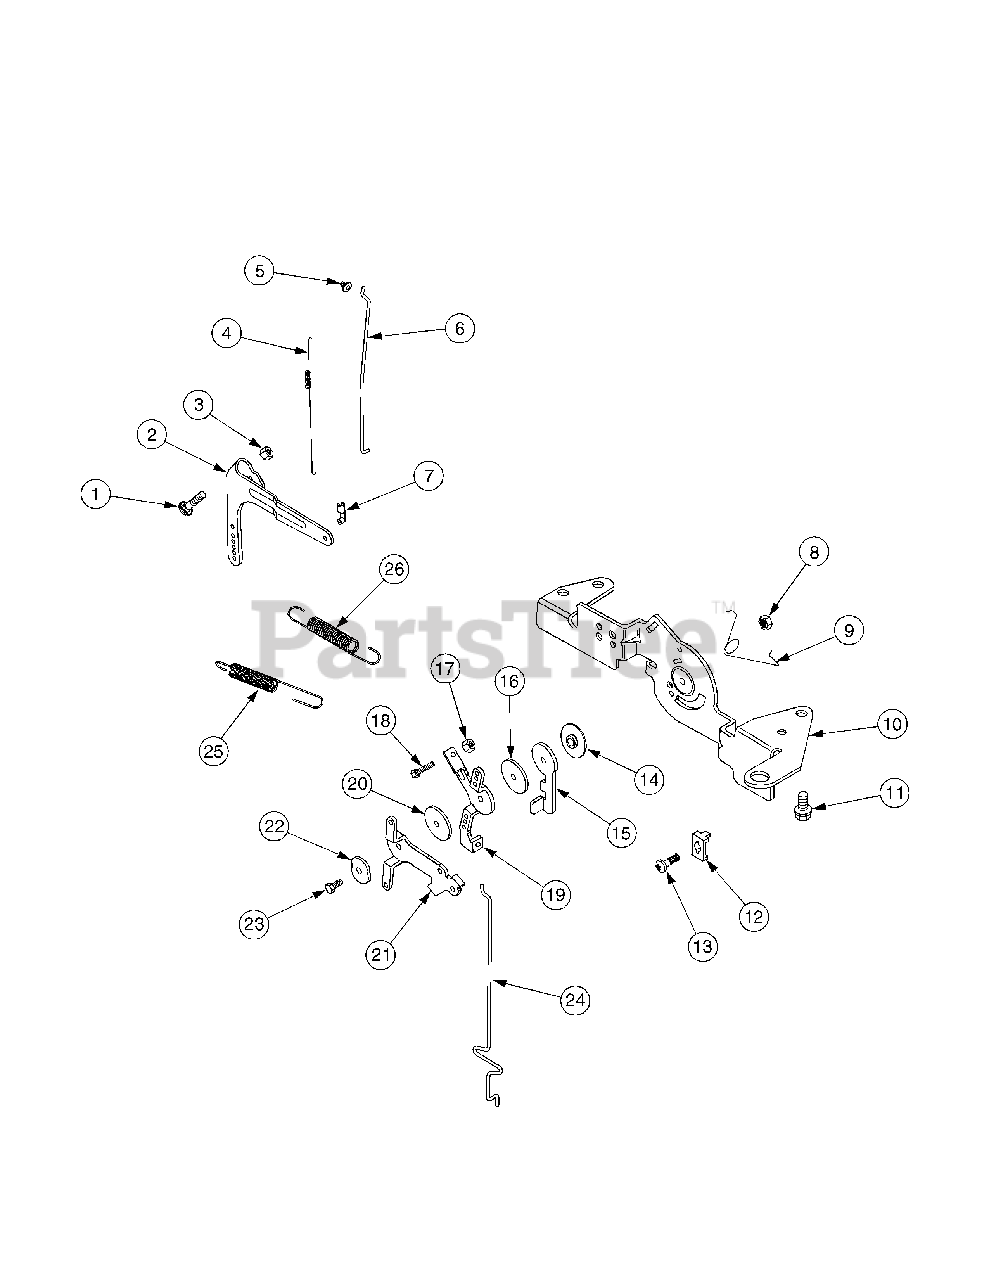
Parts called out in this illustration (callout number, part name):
1	Bolt, Round Hd, M6-1.0 x 25
2	Lever, Governor
3	Nut, Hex Flange, M6-1.0
4	Spring, Linkage
5	Bushing, Linkage Retaining
6	Linkage, Throttle
7	Bushing, Throttle Linkage
8	Nut, Hex Lock
9	Spring, Choke Return
10	Bracket, Control
11	Screw, Hex Flange
12	Clamp, Bowden
13	Screw, Thread Forming
14	Spacer, Control Assembly
15	Lever, Throttle Actuator
16	Washer, Plain
17	Nut, Hex M4 x 0.7
18	Screw, Hex. Hd, M4-0.7 x 25
19	Lever, Throttle Control
20	Washer, Plain
21	Lever, Choke
22	Washer, Wave
23	Screw, Hx Flange, M5-0.8 x 20
24	Linkage, Choke
25	Spring, Governor
26	Spring, Governor
